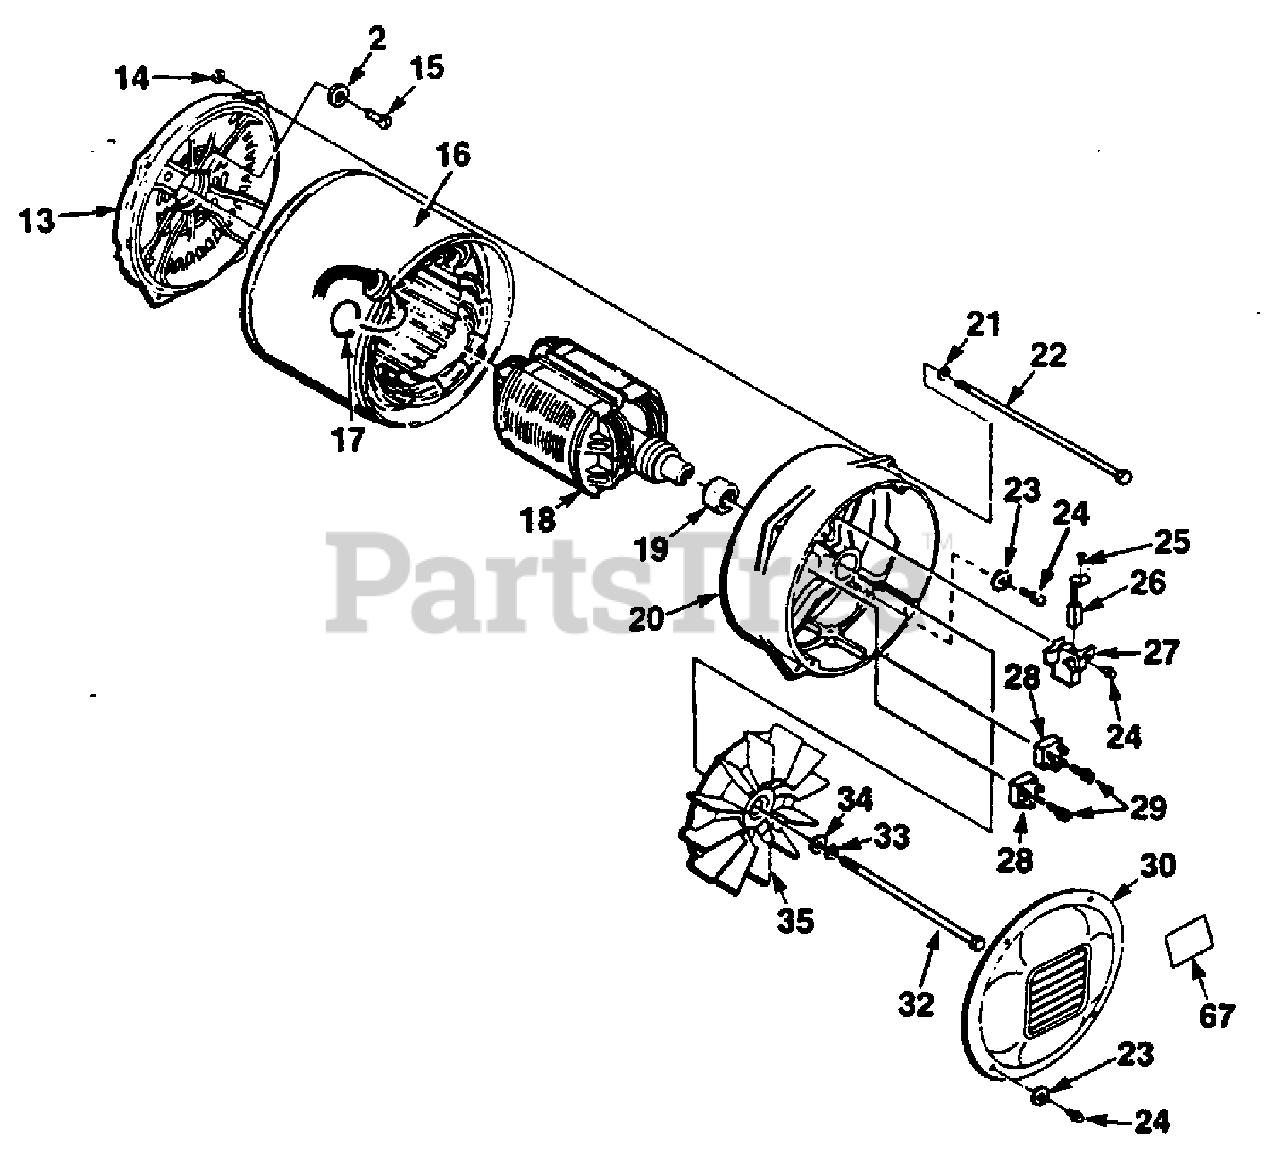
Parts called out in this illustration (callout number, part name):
2	WASHER- Lock Int. 5/16
13	ENDBELL- Gen.
14	NUT-Hex 1/4-20
15	SCREW-Hex hd., 5/16-24
16	STATOR & SHELL
17	TIE-Cable
19	BEARING
20	BRUSH HEAD
21	WASHER-Lock
22	BOLT- Stator
23	WASHER-Lock Int. #8
24	SCREW- Thread forming
25	SCREW- Mach round hd.
27	BRUSH HOLDER
28	RECTIFIER
29	SCREW- Hex taptite, 8-32 x 3/4"
30	COVER- Brush head
32	BOLT- Rotor .312-24 x 6 1/2"
33	WASHER- Lock 5/16"
34	WASHER-Flat 5/16"
67	DECAL-Warning
